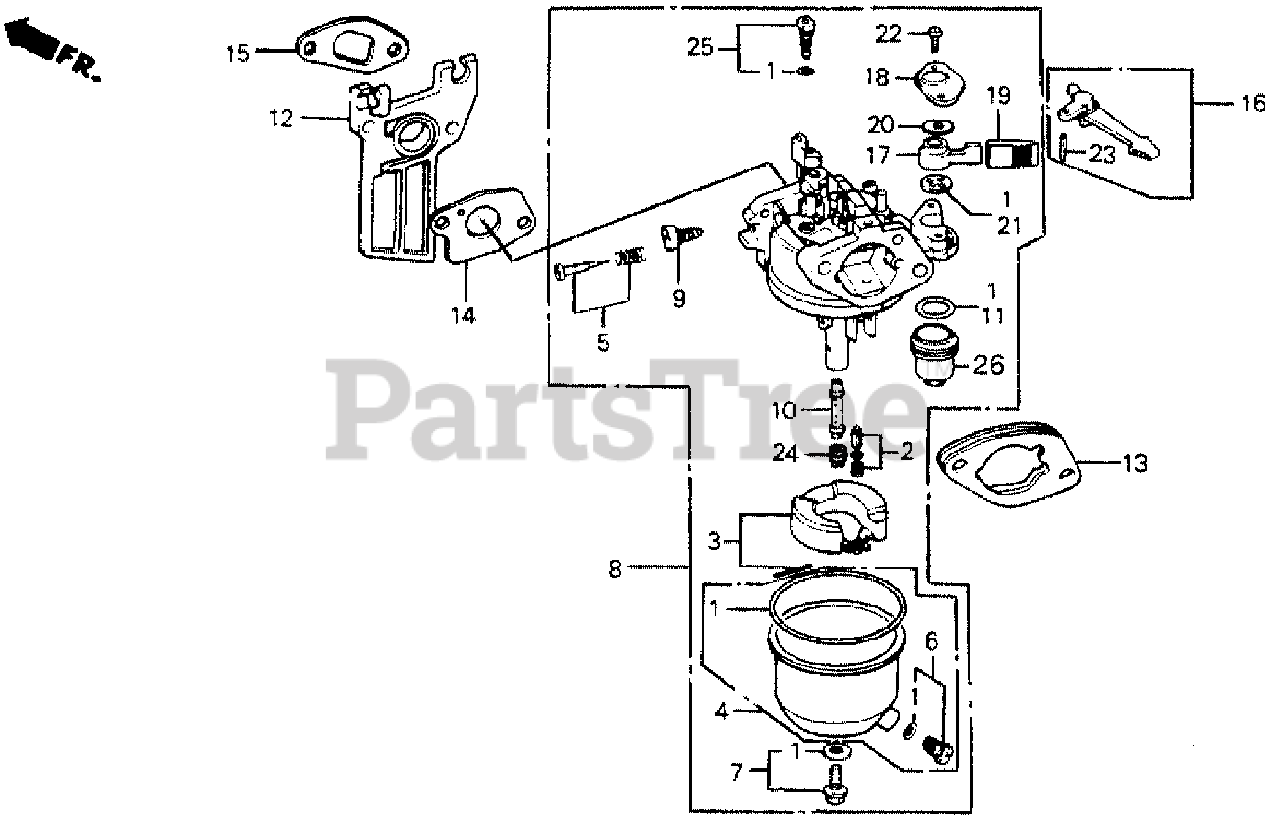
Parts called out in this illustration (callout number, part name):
1	GASKET SET
2	VALVE SET, FLOAT
4	CHAMBER SET, FLOAT
5	SCREW SET, PILOT
6	SCREW SET, DRAIN
7	SCREW SET B
8	CARBURETOR ASSY. (BE07A C)
8	CARBURETOR ASSY. (BE07A D)
8	CARBURETOR ASSY. (BE07A E)
9	SCREW, THROTTLE STOP
10	NOZZLE, MAIN
11	GASKET, FUEL STRAINER CUP
12	INSULATOR, CARBURETOR
13	SPACER, CARBURETOR
14	GASKET, CARBURETOR
15	GASKET, INSULATOR
16	LEVER, CHOKE (REMOTE)
17	LEVER, VALVE
18	PLATE, LEVER SETTING
19	CAP, LEVER
20	SPRING, VALVE LEVER
21	GASKET, VALVE
22	SCREW, PAN (3X8)
23	PIN, SPRING (2X12)
24	JET, MAIN (#65)
24	JET, MAIN (#68)
24	JET, MAIN (#70)
25	JET SET, PILOT (#35)
